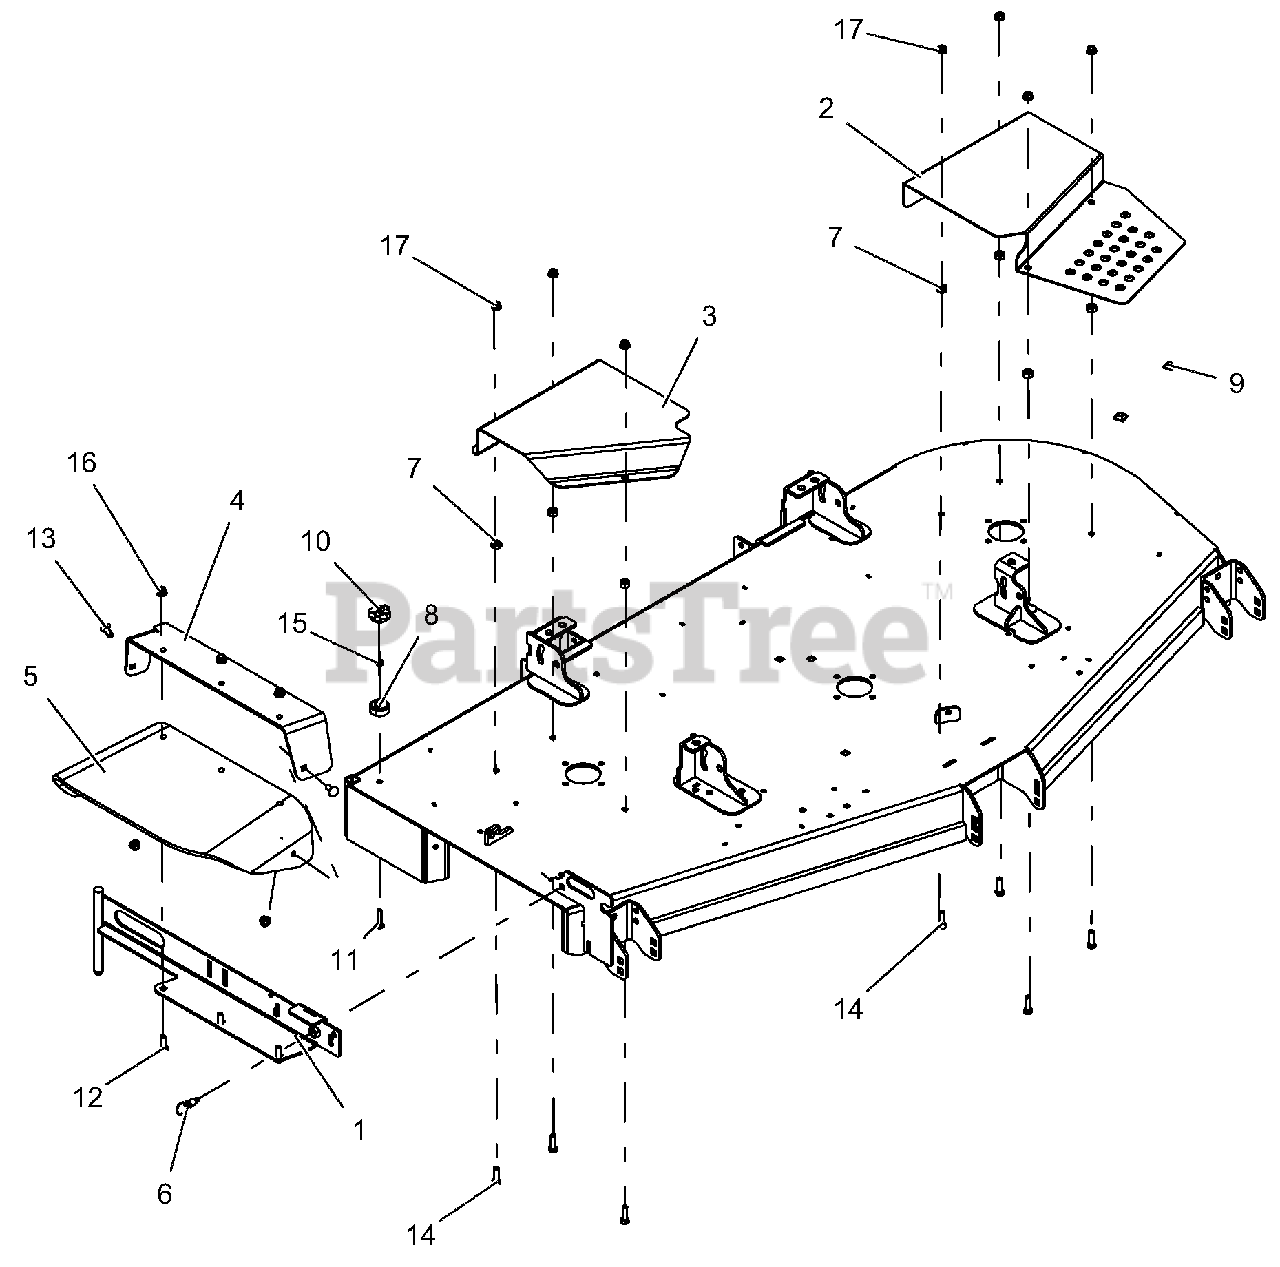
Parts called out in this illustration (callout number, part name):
1	WLDMT, 66"-72" DISCH CHUTE MTG-RED
2	GUARD, 72" LH DECK BELT-RED
3	GUARD, 72" RH DECK BELT-RED
4	SUPPORT, CHUTE MOUNTING BRACKET-RED
5	CHUTE, RUBBER DISCHARGE
6	PULL PIN,.50-13THDX.310 PLNGR
7	NUT-HEAVY HEX .38-16 YWZC
8	BUMPER, RECESSED 1.50 X .63 W/.31 HOLE
10	KNOB, CLAMPING
11	@BLT-RDHDSQNK .31-18X1.50 G5 YWZC
12	@BLT-RDHDSQNK .38-16X1.25 G5 YWZC
13	@BLT-RDHDSQNK .38-16X1.00 G5 YWZC
14	BLT-HEX .38-16X1.25 GR5 YWZC
15	@NUT-LK-CTR .31-18 YWZC
16	NUT-LK-NYL-FLG .38-16 YWZC
17	@NUT-SPNLK-FLG .375-16 YWZC
